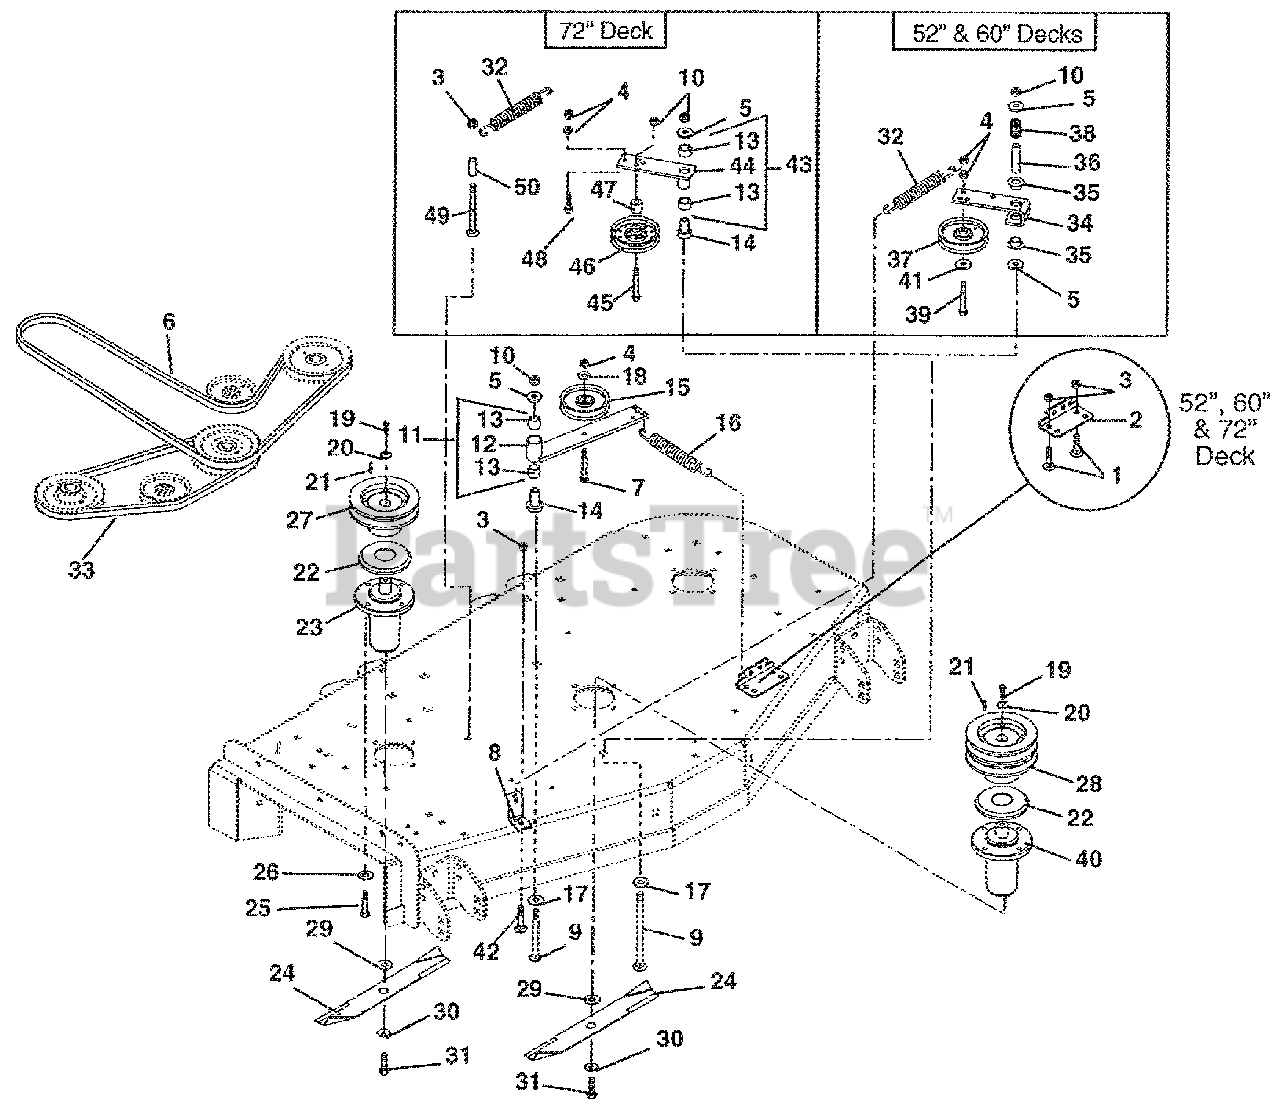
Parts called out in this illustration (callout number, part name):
1	Bolt, Round Head Square Neck .38-16 x .75 Grade 5
2	Bracket, Spring
3	Nut, Locking Top Flange .38-16 (066, 067, 068, 069, 071)
3	Nut, Locking Top Flange .38-16 (070, 072)
4	Nut, Locking Center .38-16
5	Washer, Flat Steel .531 x 1.25 x .10 (066, 067, 068, 069, 071)
5	Washer, Flat Steel .531 x 1.25 x .10 (070, 072)
6	V-Belt, B-Section 54.06 x ..625 (066, 071)
6	V-Belt, B-Section 54.06 x ..625 (067, 068, 069)
6	V-Belt, B-Section 54.06 x ..625 (0070, 072)
7	Bolt-Round Head Square Neck .38-16 x 2.75 Grade 5
8	Anchor, Spring
9	Bolt, Round Head Square Neck .50-13 x 3.50 Grade 5
10	Nut, Locking Top Flange .50-13 (066, 067, 068, 069, 071)
10	Nut, Locking Top Flange .50-13 (070, 072)
11	Assembly, Idler Pivot Arm (Contains Items 12 & 13)
12	Weldment, Idler Pivot Arm
13	Bearing, 1.00 x 1.12 x .75
14	Bearing, Pedestal Powdered Metal (066, 067, 068, 069, 071)
14	Bearing, Pedestal Powdered Metal (070, 072)
15	Idler, Flat 4.00 x .38 (2.00 W)
16	Spring, Extension
17	Washer, Flat Steel .755 x 1.375 x .062
18	Washer, Flat Steel .375 x 1.125 x .065
19	Bolt, Hex .38-16 x 1.00 Grade 8
20	Washer, Cupped Serrated .375
21	Key, Square .25 x .25 x 1.00
22	Slinger, Dust
23	Assembly, Maintenance Free Spindle
24	Blade, Mower (070, 072)
24	Blade, 32 in. (16.25) (066, 071)
24	Blade, Mower (18.00) (067, 068, 069)
24	Blade, Mower 72 in. Mulch (070, 072)
24	Blade, Mulching (18.00) (066, 071)
24	Blade, Mower 60 in. Mulch (067, 068, 069)
25	Bolt, Hex .38-16 x 1.00 Grade 5
26	Washer, Locking .38 x .094 Regular
27	Weldment, Spindle Sheave 5.00 (066, 071)
27	Weldment, Spindle Sheave 6.00 (067, 068, 069)
27	Weldment, Spindle Sheave (070, 072)
28	Sheave, Double (5.25) (066, 071)
28	Sheave, Double (6.25) (067, 068, 069)
28	Sheave, Double (7.25) (070, 072)
29	Washer, Flat .64 x 1.81 x .25
30	Washer, Bellville .6 x 1.625 x .14
31	Bolt, Hex .62-18 x 1.75 Grade 8
32	Spring, Extension
33	V-Belt 5L-Section 49.97 x .672 (070, 072)
33	V-Belt B-Section 19.10 x .672 (066, 071)
33	V-Belt B-Section 23.94 x .625 (067, 068, 069)
34	Arm, Idler Pivot
35	Bushing, Flange .762 x 1.00 x .58 x 1.48 Nylon
36	Spacer .56 x .75 x 2.44 Steel
37	V-Idler, 4.00 x .38
38	Spring, Compression .085 x .80 x 1.00
39	Bolt, Hex .38-16 x 2.25 Grade 5
40	Spindle Assembly (Center)
41	Washer, Flat Steel .406 x .812 x .065
42	Bolt, Round Head Square Neck .38-16 x 1.00 Grade 5
43	Assembly, Idler Arm Guard Drive (Includes 13 and 44) (070, 072)
44	Weldment, Idler Arm Ground Drive (070, 072)
45	Bolt, Hex .38-16 x 6.00 Grade 5 (070, 072)
46	Idler, Flat Pulley 6.75 x .51 (070, 072)
47	Spacer .513 x .748 x .62 (070, 072)
48	Bolt, Hex .38-16 x 1.25 Grade 5 (070, 072)
49	Bolt, Round Head Square Neck .38-16 x 2.75 Grade 5 (070, 072)
50	Spacer .38 x .625 x 1.50 (070, 072)
